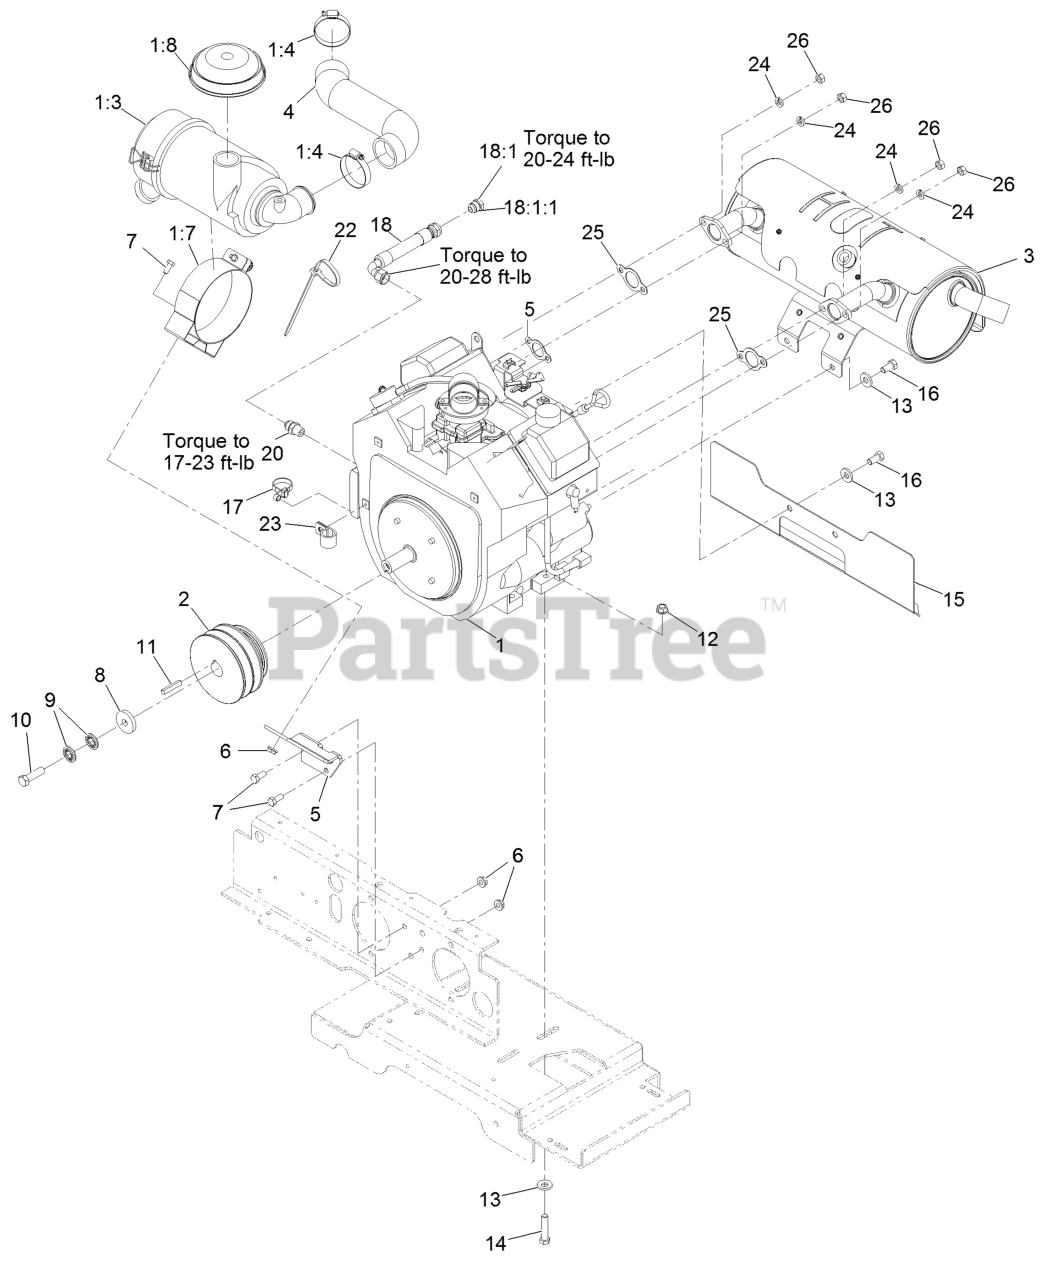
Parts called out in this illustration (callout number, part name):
1:3	AIR CLEANER CANISTER ASM
1:4	CLAMP-HOSE
1:7	BRACKET-FILTER, AIR
1:8	HOOD-CLEANER, 2" AIR INTA
4	HOSE-AIR INTAKE
5	BRACKET-FILTER, AIR
7	SCREW-HH
8	WASHER-CLUTCH
9	WASHER-SPRING
10	SCREW-HH
11	KEY-SQUARE
12	NUT-HHF, WHIZ
13	WASHER-BELLEVILLE
14	SCREW-HH
15	SHIELD-EXHAUST
16	SCREW-HH
17	Tie-Cable
18	OIL DRAIN HOSE ASM
18:1	PLUG-HH
18:1:1	O-RING
20	FITTING-STRAIGHT
22	TIE-PLASTIC
23	CLIP-LOOM
24	WASHER-LOCK
26	NUT-HEX
